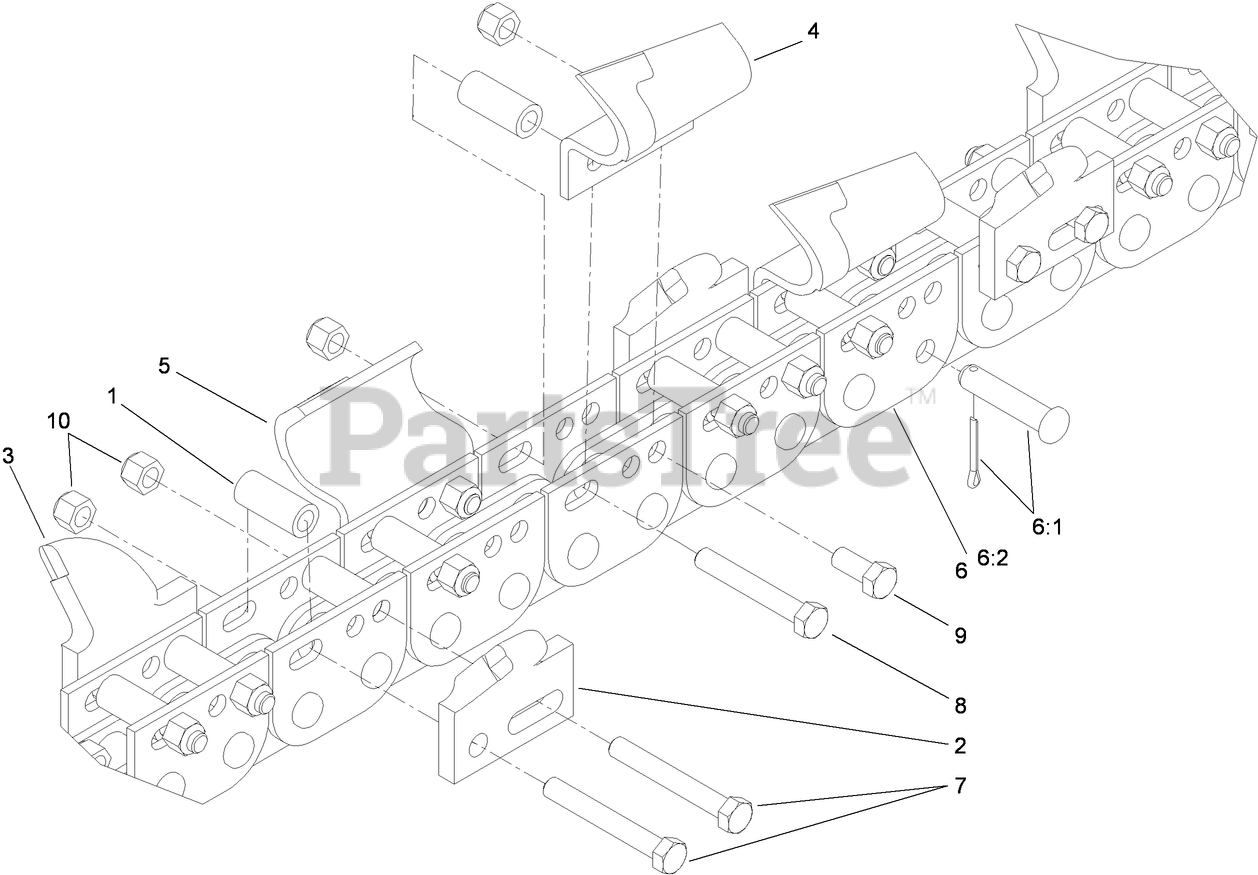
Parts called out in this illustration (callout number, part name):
1	SPACER-TUBE
2	TOOTH- ROCK, LH
3	TOOTH-ROCK, RH
4	TOOTH-SOIL, LH
5	TOOTH-SOIL, RH
6	CHAIN-BARE, 24 STATION
6:1	PIN-CONNECTING,
6:2	KIT-REPAIR, LINK
7	SCREW-HH
8	SCREW-HH
9	SCREW-HH
10	NUT-LOCK
